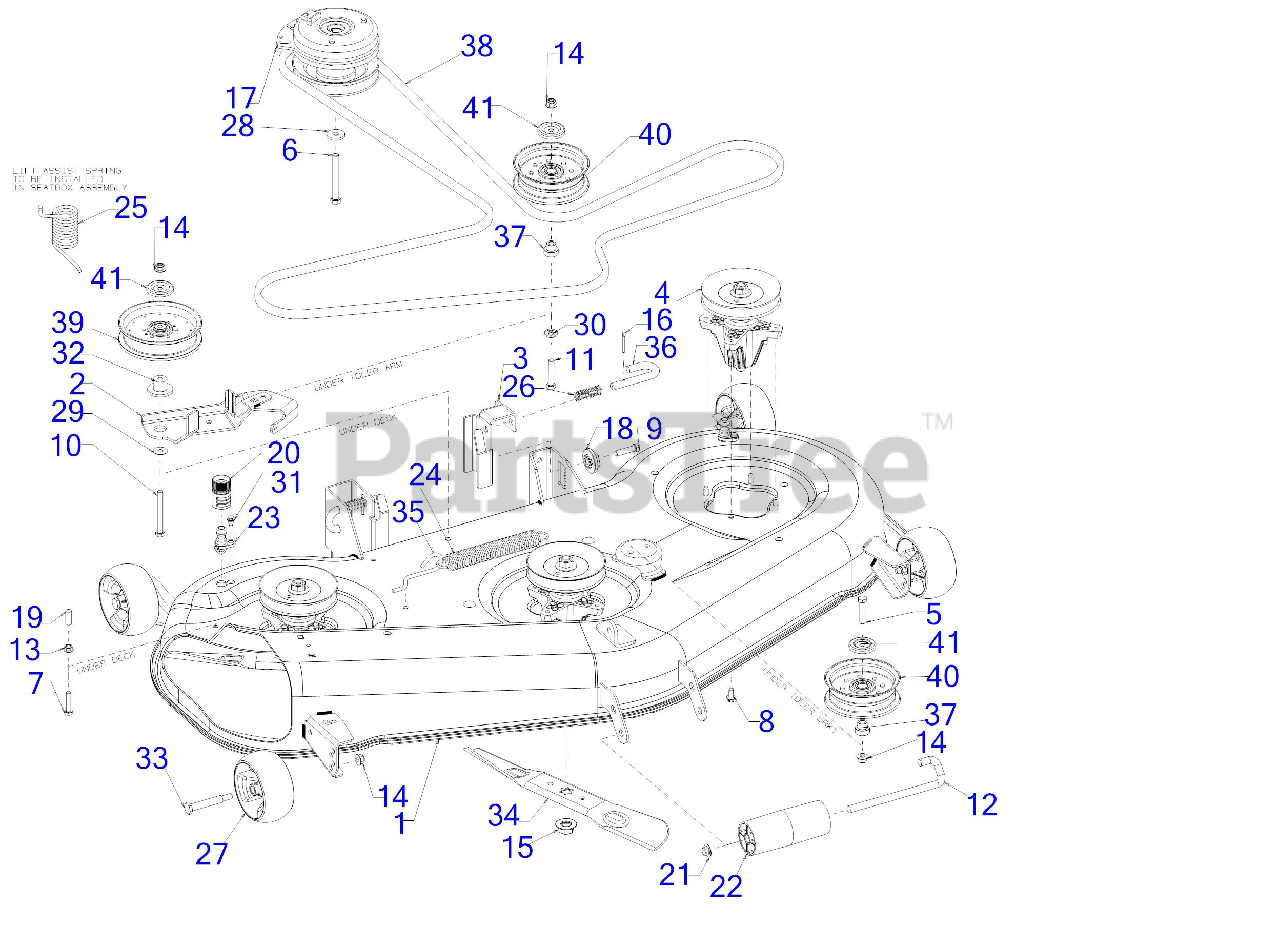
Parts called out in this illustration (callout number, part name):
2	DECK IDLER BRACKET ASSEMBLY
4	SPINDLE ASSEMBLY
5	HEX SCREW 3/8-16 x 1.75 GR5
6	SCREW 7/16-20 x 3.5 GR5
7	SCREW 5/16-18 x 1.5 LG
8	SCREW 5/16-18 x .750
9	SCREW 3/8-16X1.5 GR5
10	SCREW 3/8-16 x 3.25 GR8
11	SCREW 3/8-16 x 2.0 GR5
12	ROLLER PIN 1/2 x 7.31
13	FLANGE LOCK NUT 5/16-18
16	COTTER PIN-5/32 DIA
17	ELECTRIC PTO CLUTCH
18	DECK ADJUSTMENT GEAR
20	WATER NOZZLE
23	DECK WASH NOZZLE
24	EXTENSION SPRING
25	TORSION SPRING
26	COMPRESSION SPRING
27	DECK WHEEL
28	FLAT WASHER .445 x 1.248 x .170
29	FLAT WASHER
31	SHOULDER SCREW 1/4-20 x .50
32	SHOULDER SPACER
33	SHOULDER BOLT
34	18.61" BLADE (2N1)
35	DECK SPRING HOOK
36	DECK RELEASE PIN
37	SHOULDER SPACER
38	V-BELT B SEC x 148.25 LG
39	FLAT IDLER PULLEY
40	IDLER PULLEY 4.50" DIA
41	IDLER PULLEY CAP
